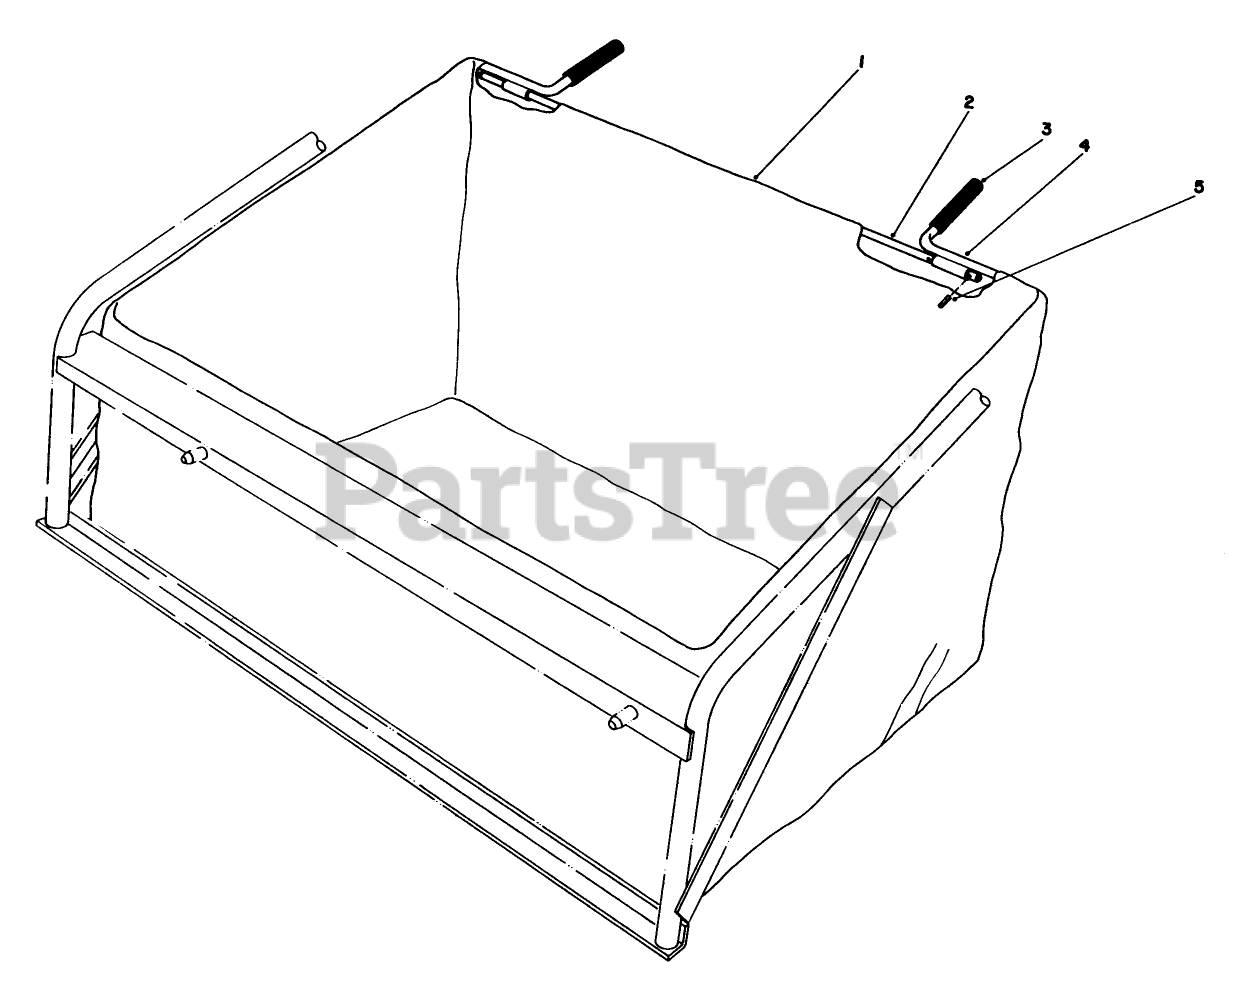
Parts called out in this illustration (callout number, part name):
2	Rod-Bag Frame
4	BAG FRAME WA *B
5	PIN-ROLL
